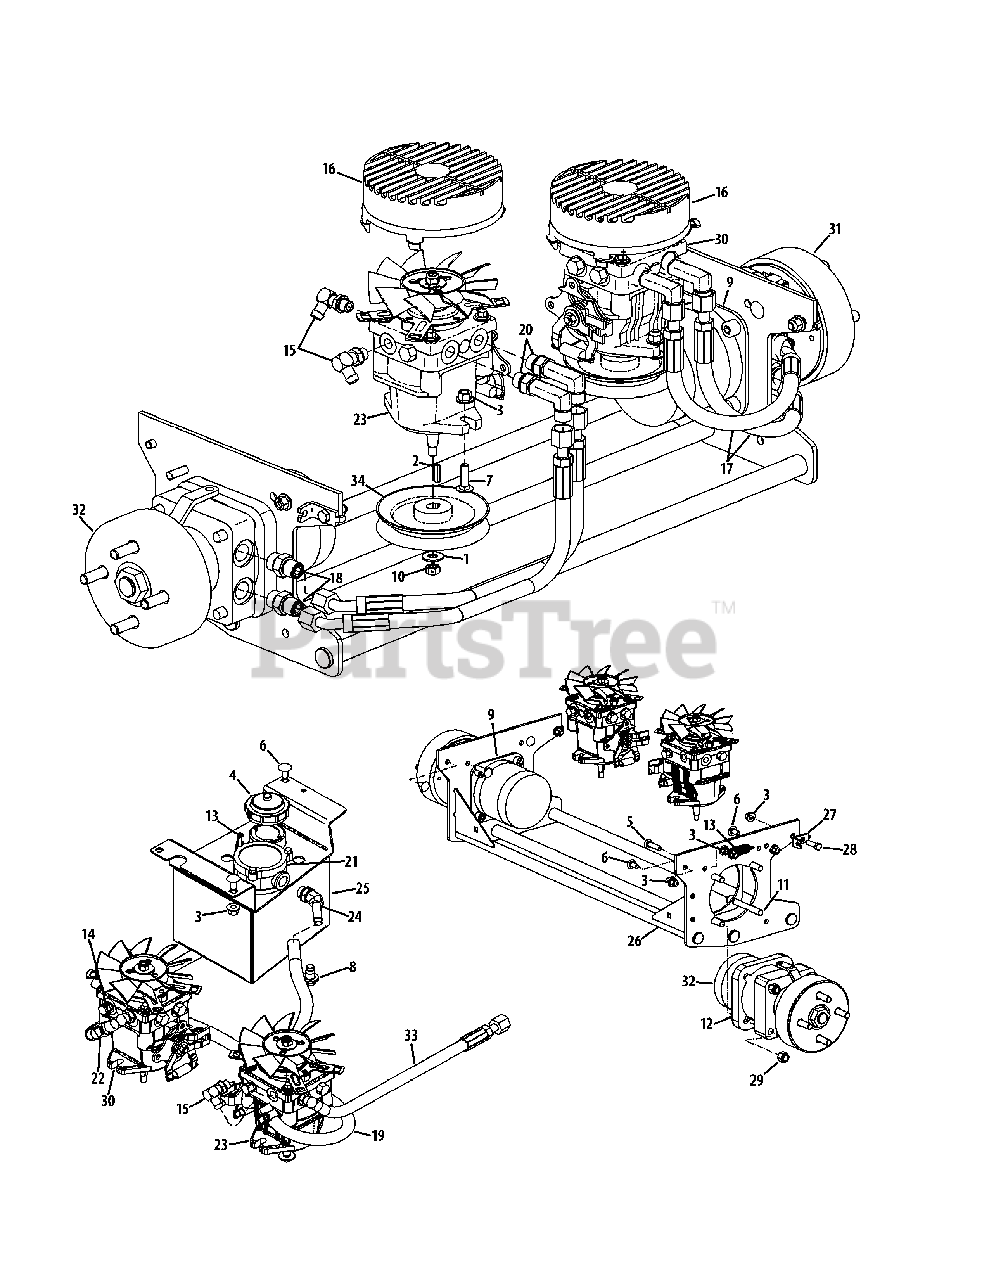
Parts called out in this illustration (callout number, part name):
1	Washer, .438 x 1.00 x .078
2	Key, .188 x .188 x .875
3	Flange Counter Lock Nut, 3/8-16
4	Hydro Oil Tank Cap
5	Carriage Bolt, 3/8-16 x 1.50
6	Carriage Bolt, 3/8-16 x .75
7	Carriage Bolt, 3/8-16 x 1.25
8	Oil Drain Plug, w/ Seal
9	Motor Back-Up Plate
10	Counter Lock Nut, 3/8-24
11	Socket Cap Screw, 1/2-13 x 3.50
12	Hydro Wheel Motor Spacer
13	Extension Spring, .74 x 2.7 x .075
14	Socket Cap Screw, 1/4-20 x .750
15	Elbow Fitting, 9/16 x 1/2
16	Pump Fan Shroud
17	Pump Motor Hose Assembly
18	Hydro Adapter, 8 x 10
19	Pilot Hydro Hose Assembly
20	Elbow Hydro Adapter, 8 x 8
21	Hydro Filter
22	Hose Clamp
23	RH Hydro Pump
24	Fitting, 3/4 x 1/2
25	Hydro Tank Assembly
26	Wide Motor Frame
27	Brake Cable Bracket
28	Hex Screw, 3/8-16 x 1.25
29	Hex Lock Nut, 1/2-13
30	LH Hydro Pump
31	LH Hydro Motor w/ Brake
32	RH Hydro Motor w/ Brake
33	Hose Assy. (Wheel Pump-Manifold)
